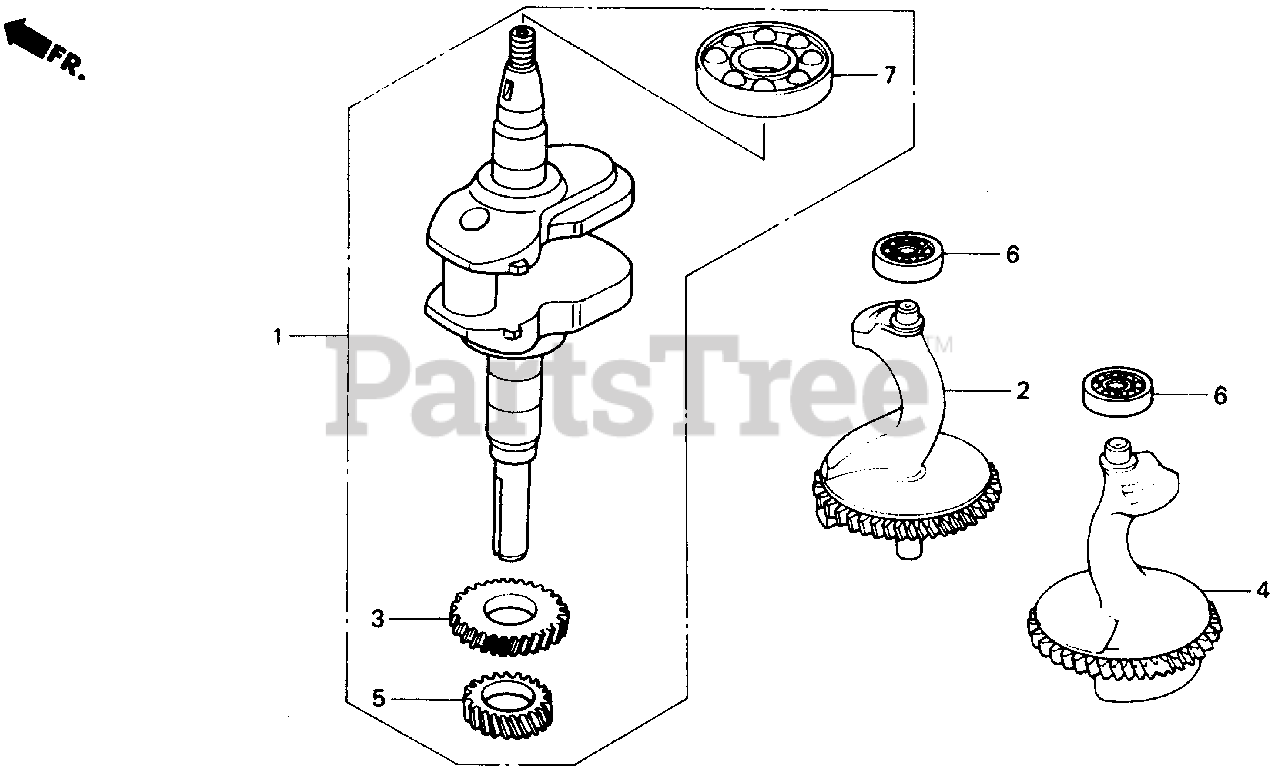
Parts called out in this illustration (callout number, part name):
1	CRANKSHAFT (NOT AVAILABLE)
2	WEIGHT A, BALANCER
3	GEAR, BALANCER DRIVE
4	WEIGHT B, BALANCER
5	GEAR, TIMING
6	BEARING, RADIAL BALL (6202)
7	BEARING, RADIAL BALL (6207)
